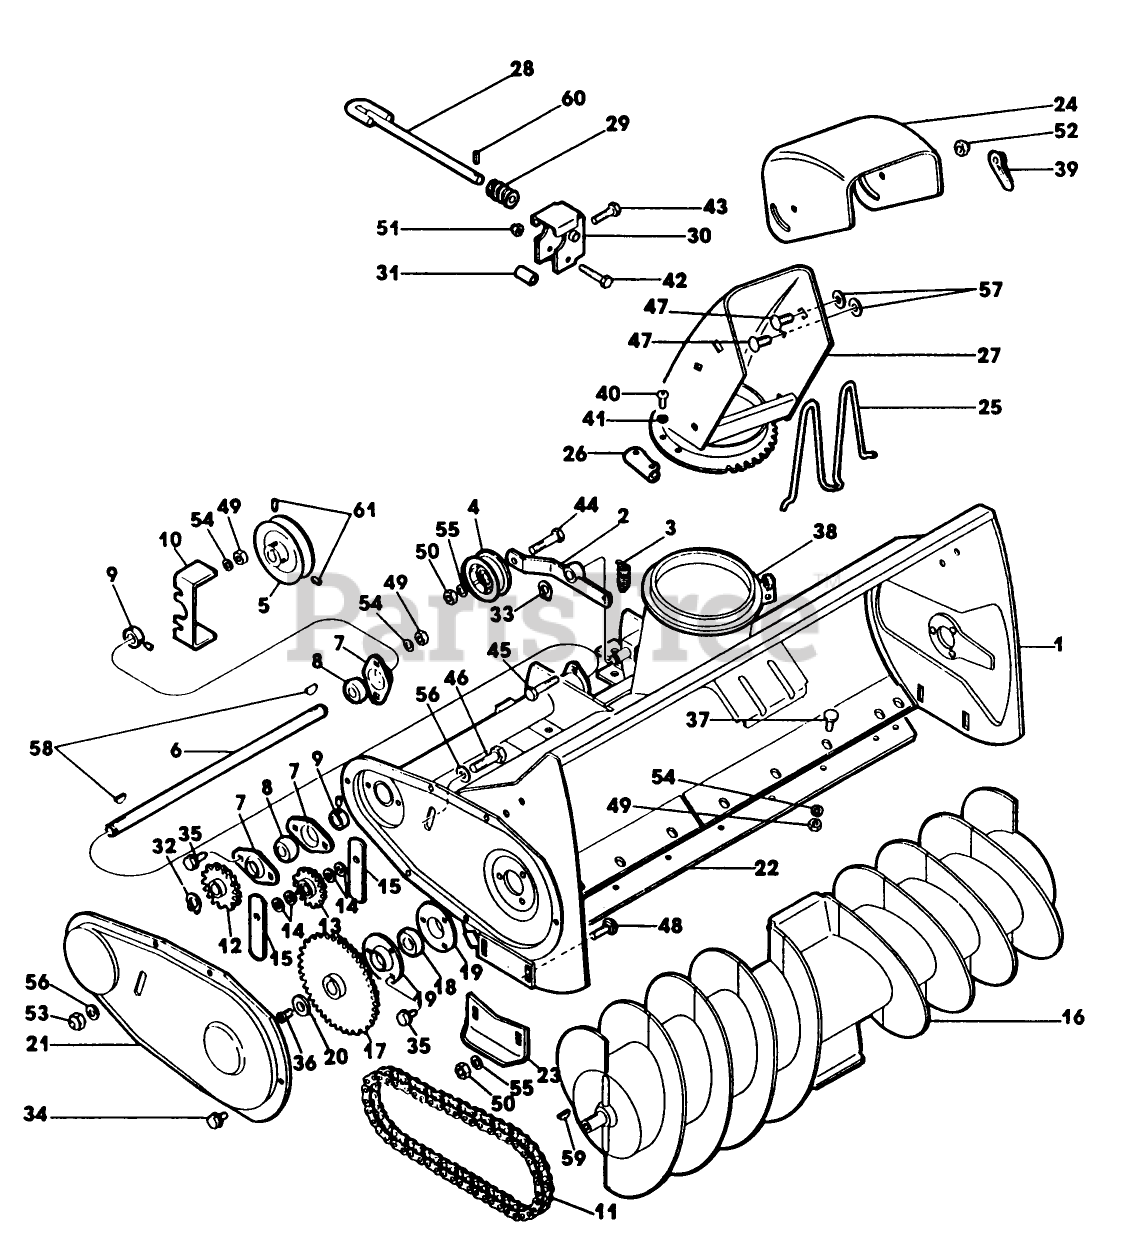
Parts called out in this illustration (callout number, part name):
7	FLANGETTE-BEARING
8	DISCONTINIUED
9	COLLAR-BEARING
12	SPROCKET ASSEMBLY
26	RETAINER
32	RING-RETAINING
51	NUT-LOCK, CONE
52	NUT-LOCKING
53	NUT-HEX CONE LOK
61	SET SCREW
